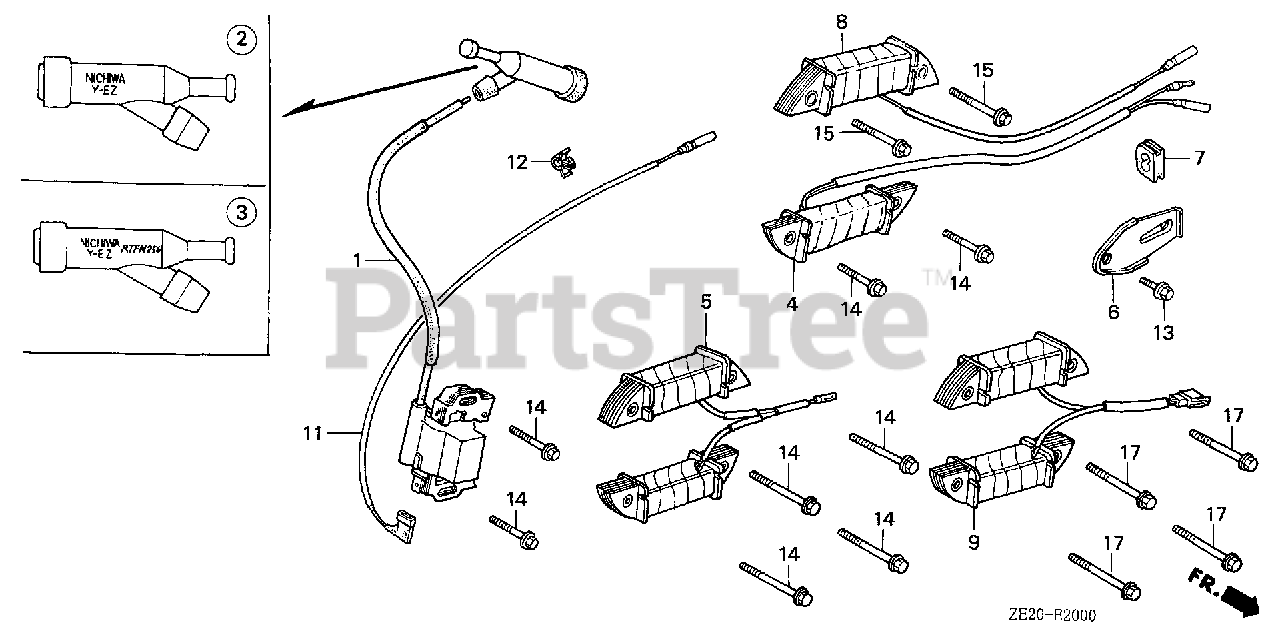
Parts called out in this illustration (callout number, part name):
1	COIL ASSY., IGNITION
3	CAP ASSY., NOISE SUPPRESSOR (NICHIWA Y-EZ RTFM256)
7	GROMMET, WIRE
11	WIRE, STOP SWITCH (370MM)
11	WIRE, STOP SWITCH (NOT AVAILABLE)
12	HOLDER, STOP SWITCH WIRE
14	BOLT, FLANGE (6X28) (CT200)
